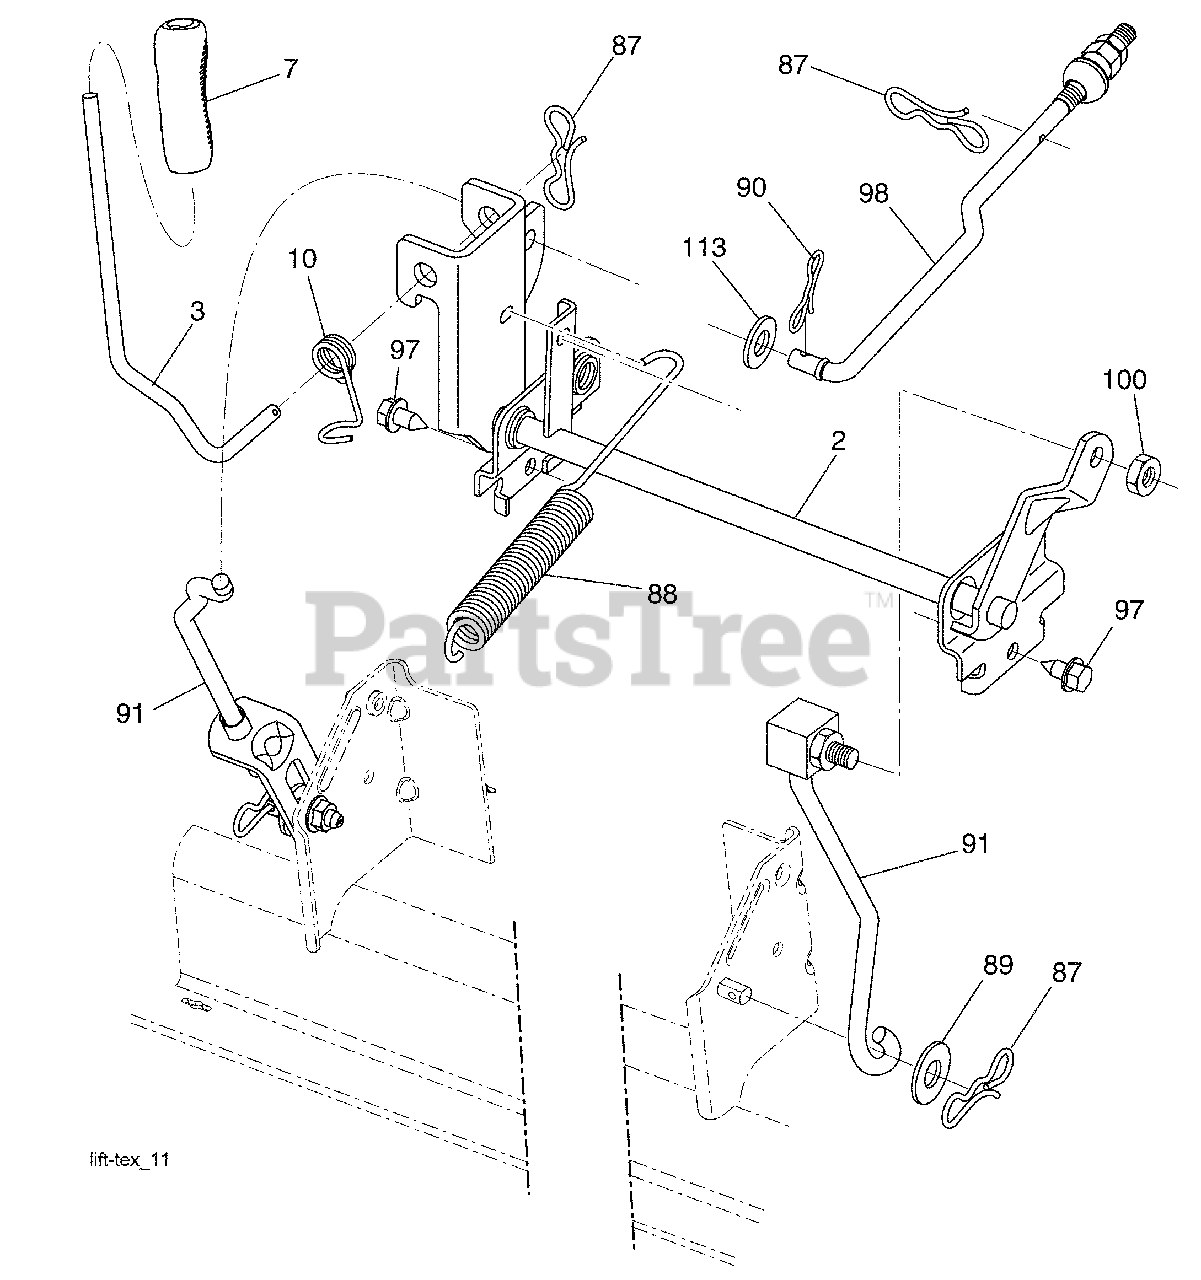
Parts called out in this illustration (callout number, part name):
2	Shaft Asm., Lift
3	Lever Asm., Lift RH
7	Grip, Lever
10	Spring Torsion
87	Pin Cotter 7/16 Bow Tie Lock
88	Spring Lift Assist
89	Washer Clear Zinc
90	Pin Cotter 5/16 Bow Tie Lock
91	Link Lift Susp Mower Rear
97	Screw 3/8-16 x 3/4
98	Link Lift Susp. Front Mower
100	Nut Center Lock 3/8-16 unc
113	Washer 17/32 x 1-3/16 x 12 Ga.
